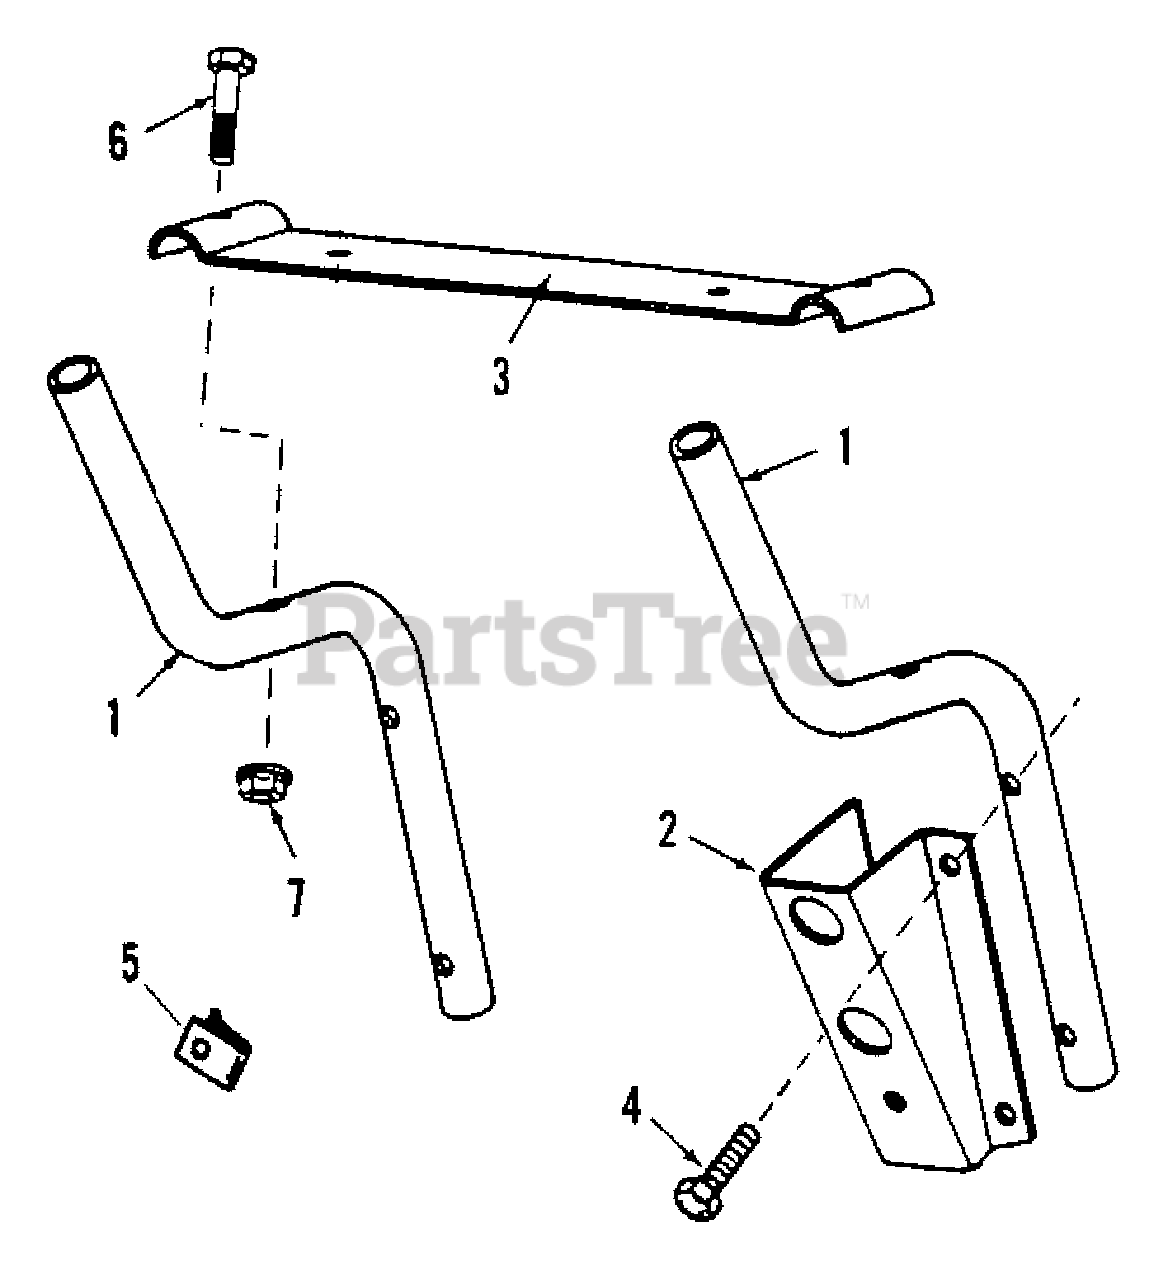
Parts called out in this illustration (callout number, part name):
1	BUMPER
2	BRACKET
4	BOLT, 5/16-18 x 2" Hex Flange Lock, Grade 5
5	NUT, 5/16" Push-on
6	SCREW, 1/4-20 x 1-1/2" Hex Head Cap, Grade 5
7	NUT, 1/4-20 Hex Flange Lock, Grade 5
